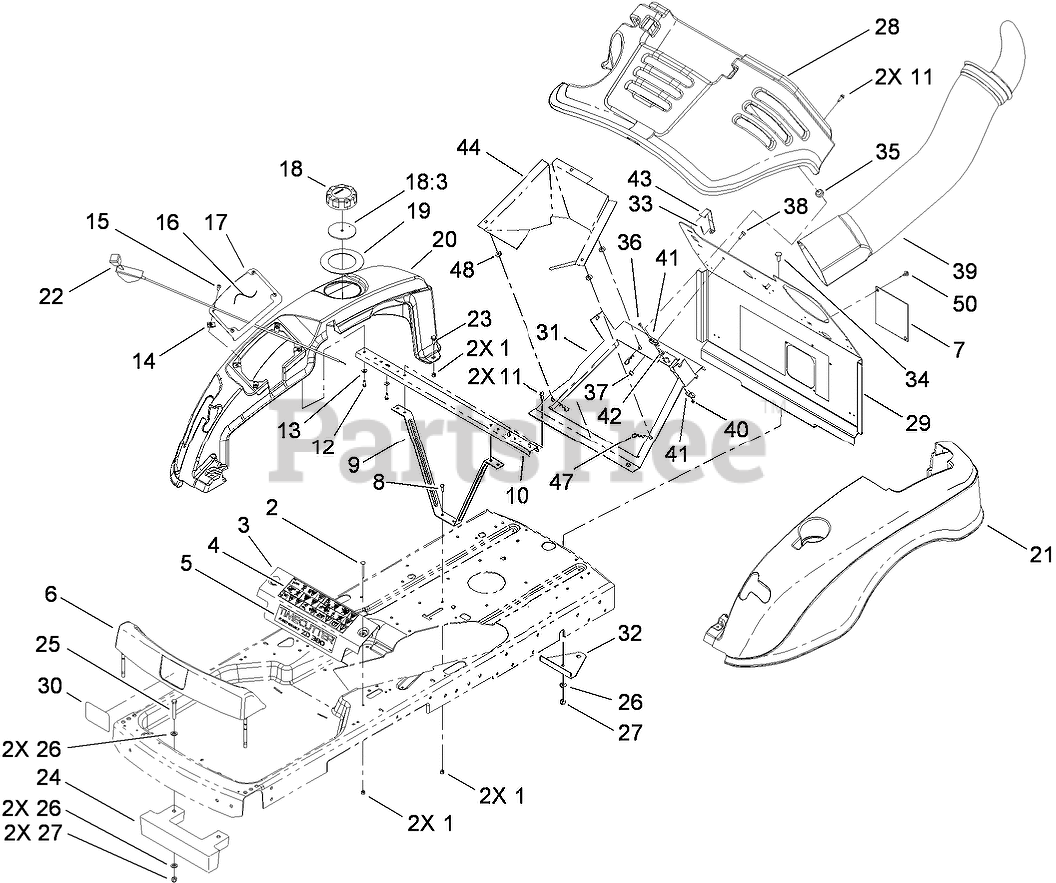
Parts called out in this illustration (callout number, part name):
1	NUT-LOCK, NI
2	SCREW-CARR
3	BRACKET-SUPPORT, FRONT
4	DECAL-DANGER
6	FOOTREST ASM
7	ACCESS DOOR ASM
8	SCREW-HH
9	BRACE ASM
10	CHANNEL-CROSS
11	SCREW-HWH, THREAD ROLL
12	SCREW-PLASTITE
13	WASHER-FLAT
15	SCREW-PRH
16	DECAL-CONTROL
17	PANEL-CONTROL
18	GAS CAP ASM
18:3	GASKET-CAP, GAS
19	SEAL-RUBBER
20	COVER-SIDE, RH
21	COVER-SIDE, LH
22	CABLE-THROTTLE
23	SCREW-SHOULDER
24	WEIGHT-BAGGER
25	SCREW-HH
26	WASHER-FLAT
27	NUT-LOCK, NI
28	COVER-ENGINE
29	SHIELD-HEAT, BAG
31	OFFSET HINGE ASM
32	HITCH-TRAILER
33	PIN-COTTER
34	SCREW-CARR
35	GROMMET
36	SCREW-HSBH
37	NUT-LOCK, NI
38	SCREW-HH
39	TUBE-DISCHARGE
40	NUT-LOCK, NI
42	PIN-HOOD
43	TAB-SWITCH
44	DUCT-FAN, ENGINE
47	PIN-HAIR
48	WASHER-RUBBER
50	SCREW-HHFTF
